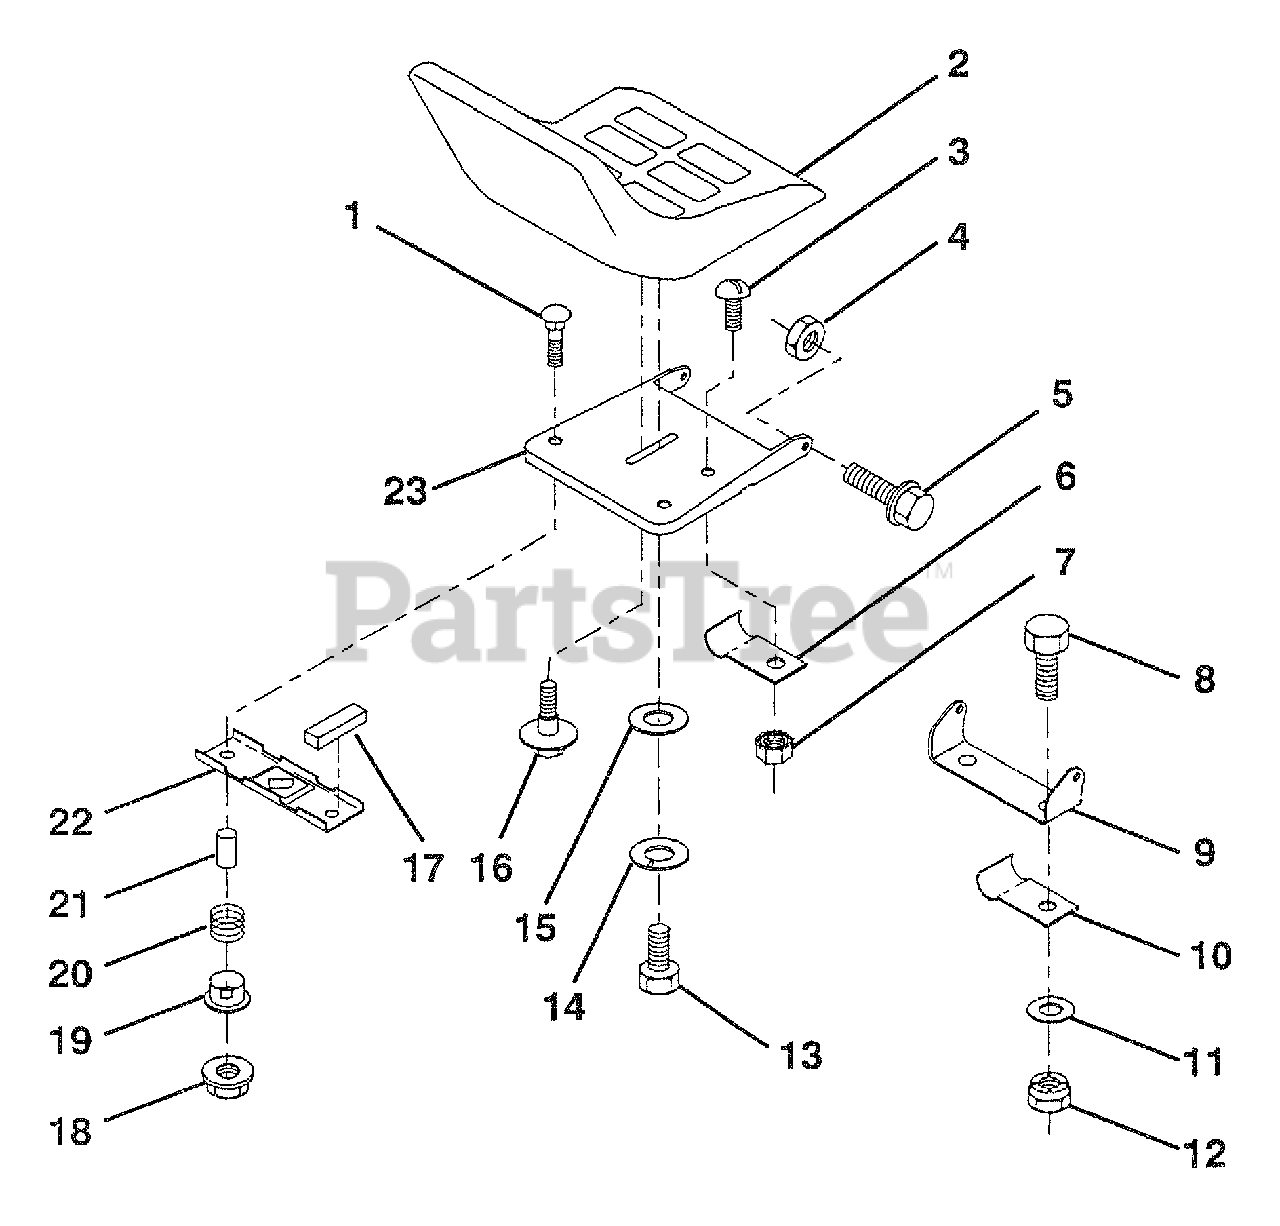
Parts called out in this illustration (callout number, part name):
1	Bolt, Carriage 1/4-20 x 1-3/8
2	Seat
3	Screw, Slotted Pan Head #10-32 x 1/2
4	Nut, Crownlock 5/16-18
5	Bolt, Shoulder 5/16-18 UNC
6	Clip, Insulated
7	Nut, Keps #10-32 UNF
8	Bolt, Fin Hex 3/8-16 UNC x 3/4
9	Bracket, Pivot Seat
10	Clip, insulated
11	Washer 12/32 x 2 x 10 Ga.
12	Nut, Crownlock 3/8-16 UNC
13	Bolt Hex 1/2-13 x 7/8
14	Washer Lock Hvy. Helical Spring 1/2
15	Washer, 17/32 x 1-3/16 x 12 Ga.
16	Bolt, Shoulder
17	Strip, Foam
18	Nut, Hex Large Flange Lock
19	Bushing, Snap
20	Spring, Compression
21	Spacer, Split 28 Id. x .88 Lg.
22	Bracket, Switch, Mounting
23	Pan, Seat
